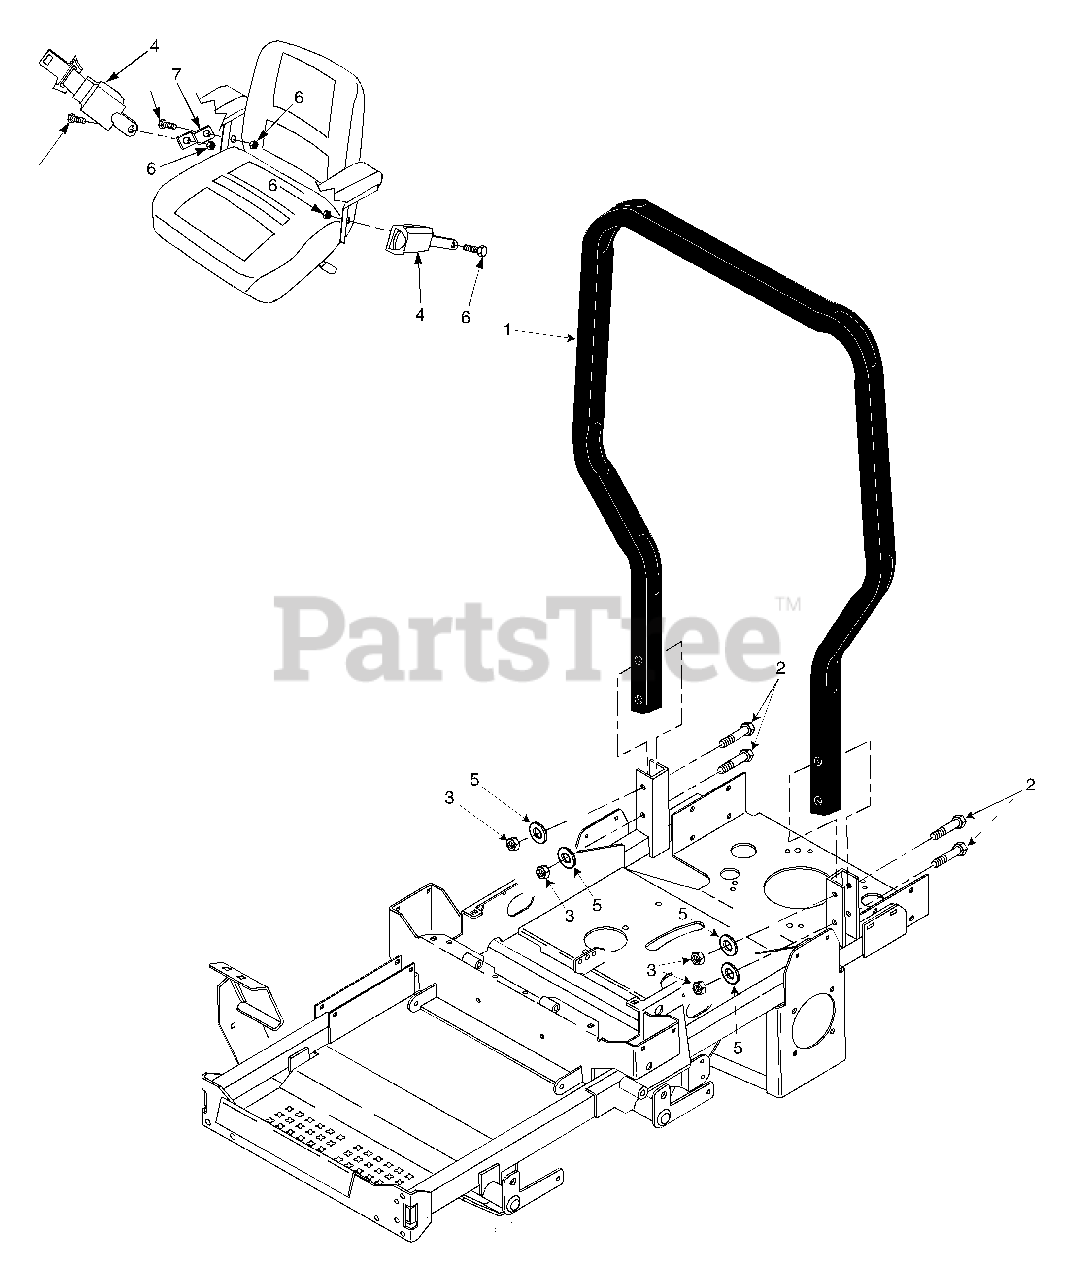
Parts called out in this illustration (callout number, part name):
1	STC Fixed ROPS Accessory
2	Bolt, Hex Head 1/2-13 x 3-1/2"
3	Nut, Center Lock 1/2-13
4	Retractable Seat Belt
5	Flatwasher, 1/2-.562 x 1.375 x .109
6	Seat Hardware Kit, STC
7	Bracket
